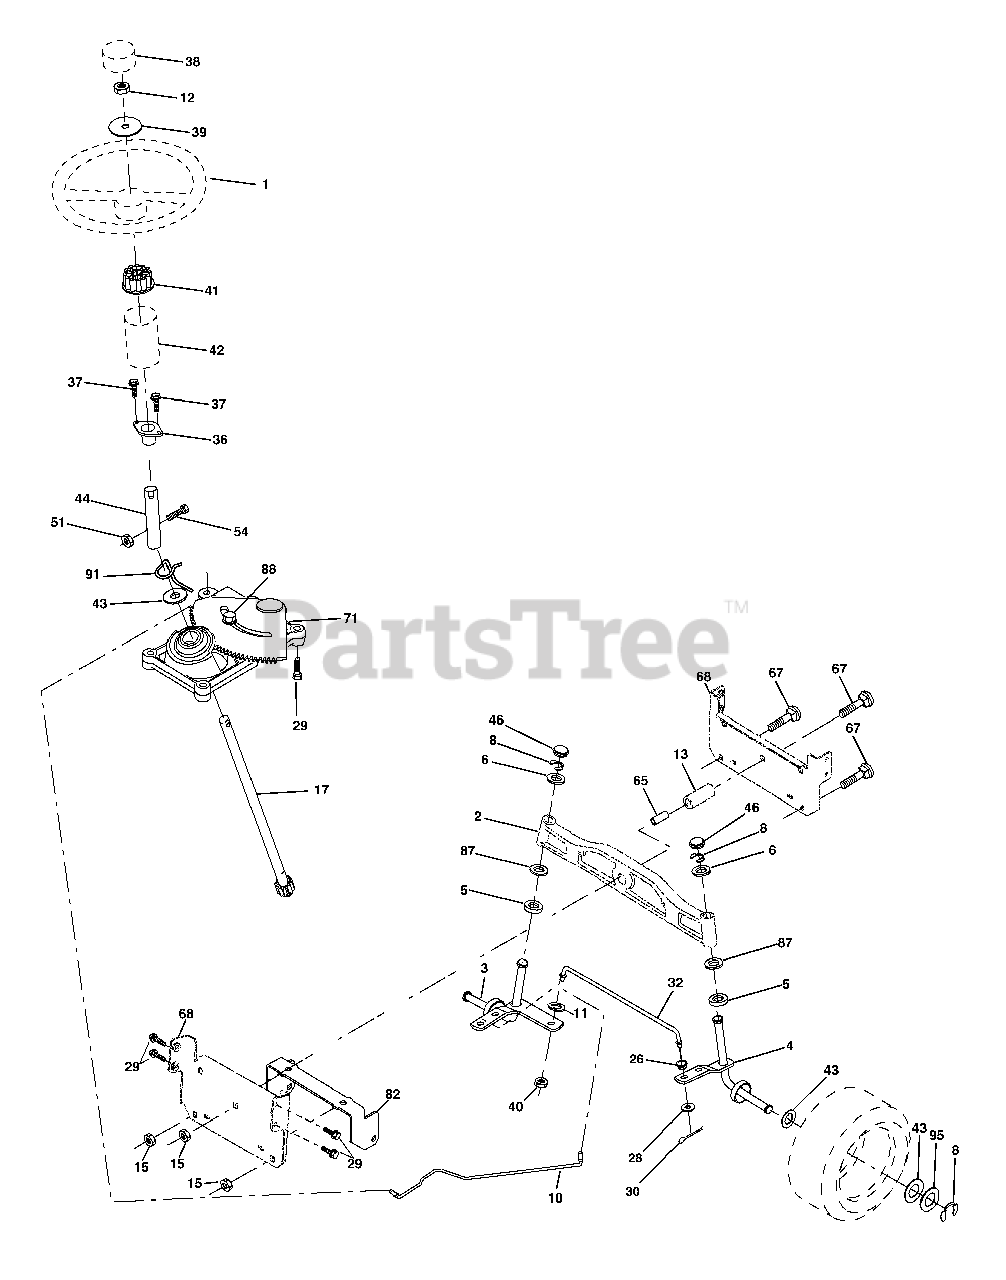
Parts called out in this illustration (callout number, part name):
1	Steering Wheel
2	Axle Assembly
3	Spindle Assembly, L.H.
4	Spindle Assembly, R.H.
5	Bearing, Race, Thrust, Hardened
6	Washer 25/32 x 1-5/8 x 16 Ga.
8	Ring, Klip
10	Draglink
11	Washer, Lock
12	Nut Hex Jam Toplock 1/2-20 Unf
13	Spacer Bearing Axle Front
15	Nut, Hex Flange Lock
17	Shaft Assembly, Steering
26	Bushing, Link, Drag
28	Washer 13/32 x 7/8 x 16 Ga.
29	Screw 3/8-16 x 3/4
30	Pin Cotter
32	Rod, Tie
36	Bushing, Steering
37	Screw
38	Insert, Steering Wheel
39	Washer 9/16 x 1-1/2 11 Ga.
40	Nut Crownlock 3/8-24
41	Adaptor, Steering Wheel
42	Boot, Steering Shaft
43	Washer 25/32 x 1-1/4 x 16 Ga.
44	Extension Shaft Steering
46	Cap, Spindle
51	Nut Crownlock 1/4-28
54	Bolt Hex 1/4-28 UNF x 1-1/4 Gr. 8
65	Spacer Brace Axle
67	Bolt RDHD Sqnk 3/8-16 x 2-1/4
68	Axle, Brace
71	Steering Asm.
82	Bracket Susp. Chassis Front
87	Washer Flat
88	Bolt Shoulder 7/16-20 Unc
91	Clip Steering
95	Washer Hardened
